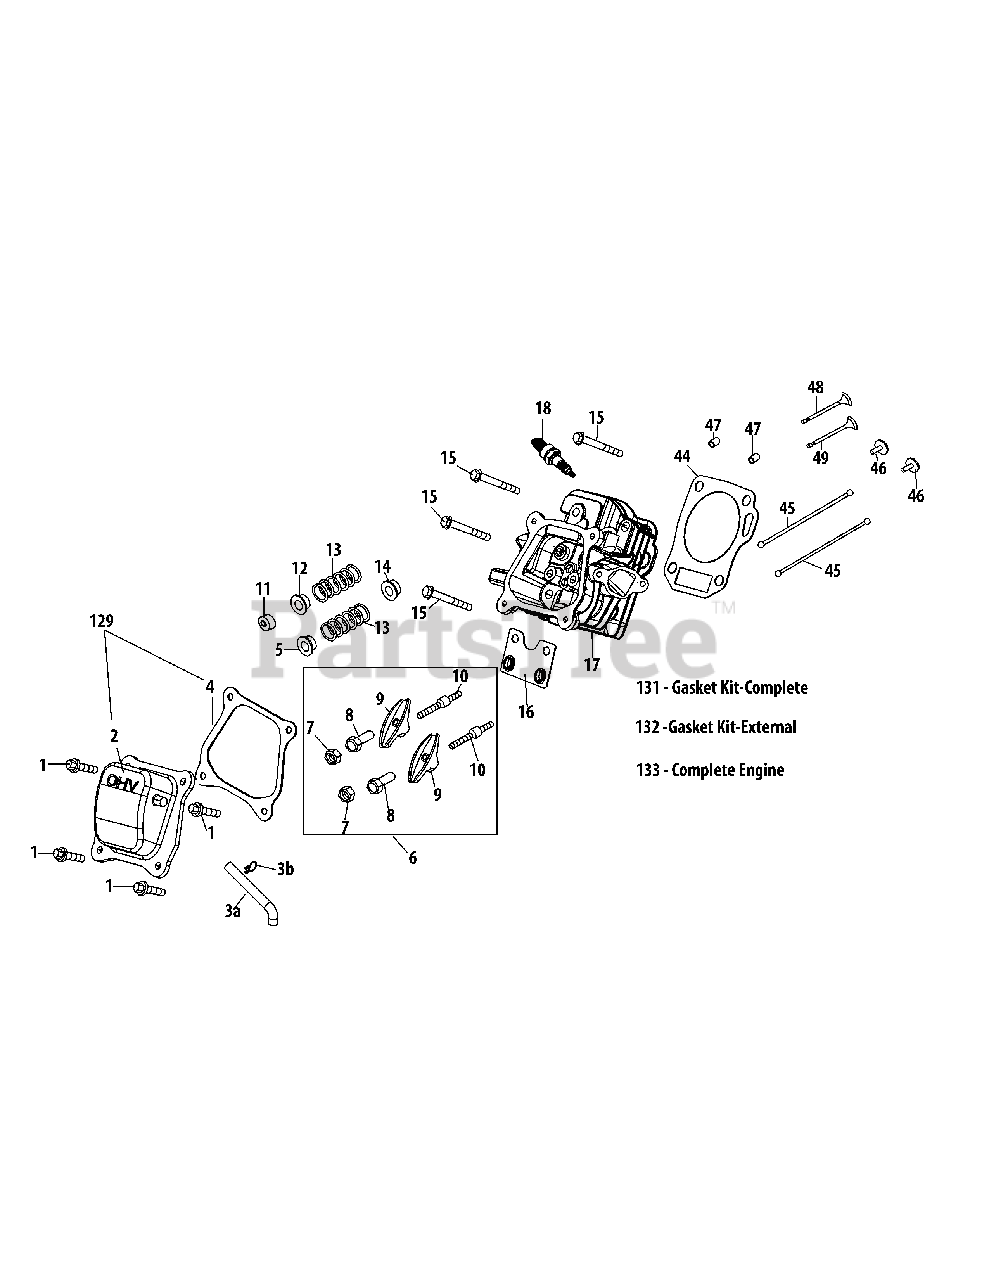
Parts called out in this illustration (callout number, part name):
1	Flange Bolt M6
2	Valve Cover
4	Valve Cover Gasket
5	Intake Valve Spring Retainer
6	Rocker Arm Assembly
7	Nut - Pivot Lockin
8	Nut - Valve Adjust
9	Rocker Arm
10	Bolt - Pivot
11	Exhaust Valve Adjuster
12	Exhaust Valve Spring Retainer
13	Valve Spring
14	Intake Valve Seal
15	Bolt - M8 X 55 Zin
16	Push Rod Guide
17	Cylinder Head Assembly
18	Plug:Spark
44	Gasket-Cylinder Head
45	Kit-Push Rod
46	Tappet
47	Pin-Dowl 10 X 16
48	Valve Kit
49	Valve Kit
129	Valve Cover Kit
131	Gasket Kit-Complete
132	Gasket Kit-External
133	Complete Engine
